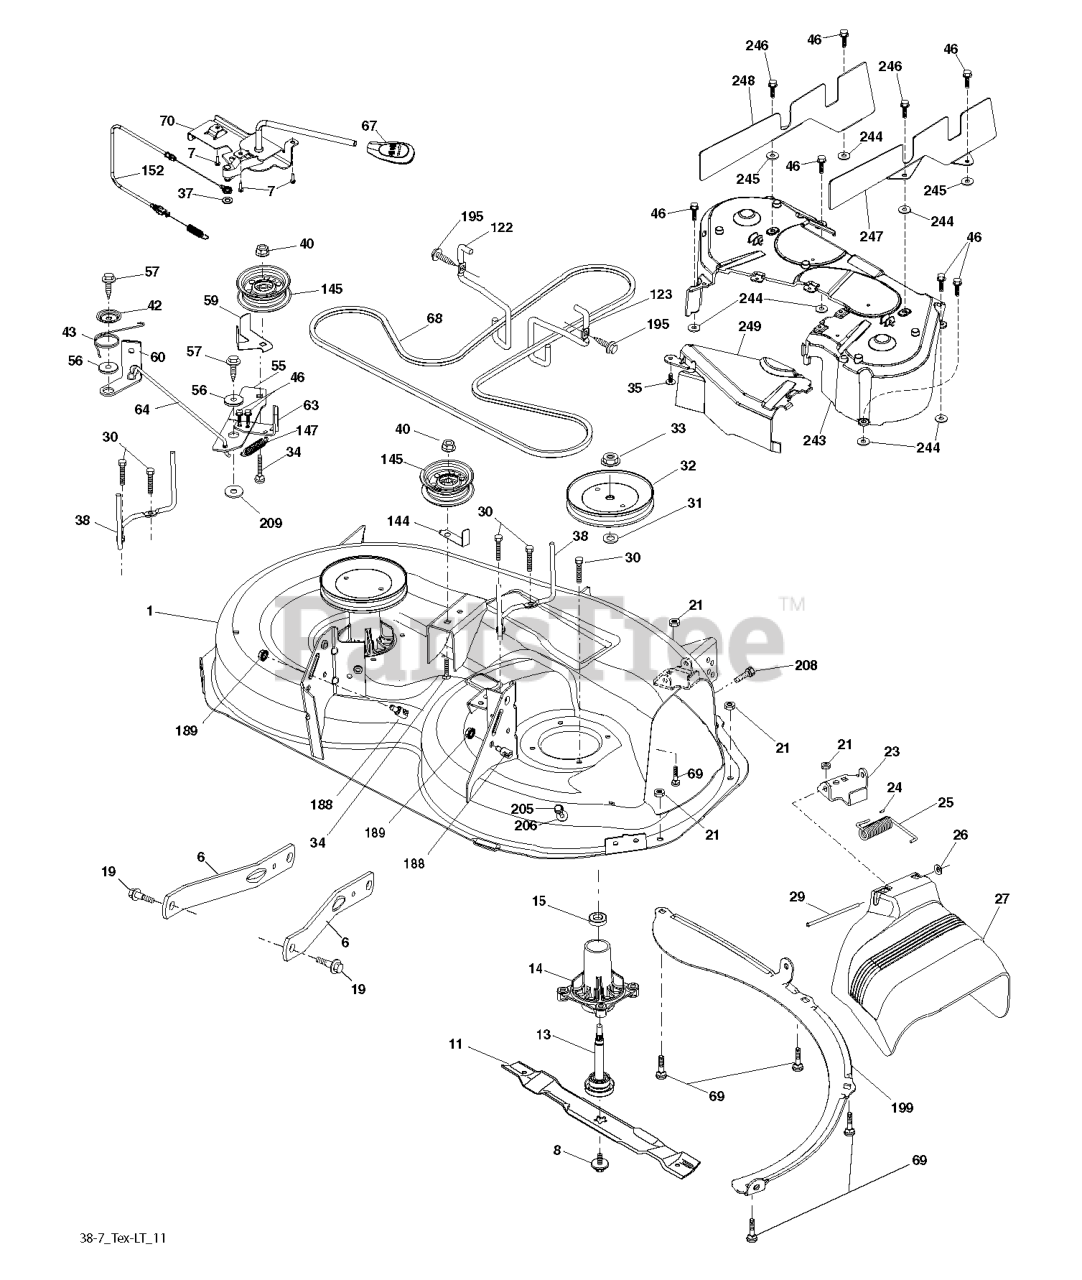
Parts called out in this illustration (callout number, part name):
1	HOUSING
6	ARM.SUSPENSION.MOWER.R
7	SCREW.#10 X 0.750.BOS
8	BOLT.WASHER.ASM.7/16-2
11	BLADE 38" PREMIUM
13	SHAFT.ASM.MDRL.N/GREASE.38
14	RP.HOUSING.MANDREL.4PT.
19	BOLT.SHOULDER
21	LOCKNUT
23	BRKT.DEFLECTOR.38"2005+
24	CAP-SLEEVE LT
25	SPRING.TORSION.DEFLECT
26	NUT PUSH M
27	SHIELD ASM.DFLCTR MWR.38-7"BLK
29	ROD.HINGE
30	SCREW, WASHER HEAD
31	WASHER.SPACER.MANDREL
32	PULLEY.MANDREL.5.0.PD.38"
33	NUT.FLANGE.LOCK.TOP
34	BOLT.3/8-16X1.50
35	FASTENER.XMAS.TREE
37	WASHER
38	KEEPER BELT LH MANDREL
40	NUT LOCK FLG 3/8-16 UNC
42	SRPING.TORSION.RETAINE
43	SPRING.TORSION.BRAKE
46	SCREW.1/4-20X5/8
56	SPACER.RETAINER
57	SCREW 3/8-16X1
59	GUARD, BELT
60	ARM BRAKE MOWER RH 38"
63	RP ARM.BRAKE.MOWER.38"LH.TEX
64	LINK BRAKE
67	HANDLE.CLUTCH.CABLE.LT
69	BOLT
70	CLUTCH.ASM.MANUAL.LT.PRED
122	KEEPER BELT ENGINE LH
123	KEEPER BELT RH
144	KEEPER BELT
145	PULLEY.IDLER.48"PRIMARY
147	SPRING RETURN
152	CLUTCH CABLE
188	STUD.FASTNER.W/ANTI-ROTATE
189	NUT LOCK HEX FLANGE 5/16-18
195	SCREW, 3/8-16X3/4
199	BAFFLE.VORTEX.FRONT.38"
205	SCREW
208	SCREW 3/8-16X1/2
209	WASHER 12/32X2X10GA
243	COVER DECK 38-7
244	PALNUT 1/4
245	WASHER 5/16"
246	SCREW, 5/16-18 X 1/2
249	COVER CABLE CLUTCH
